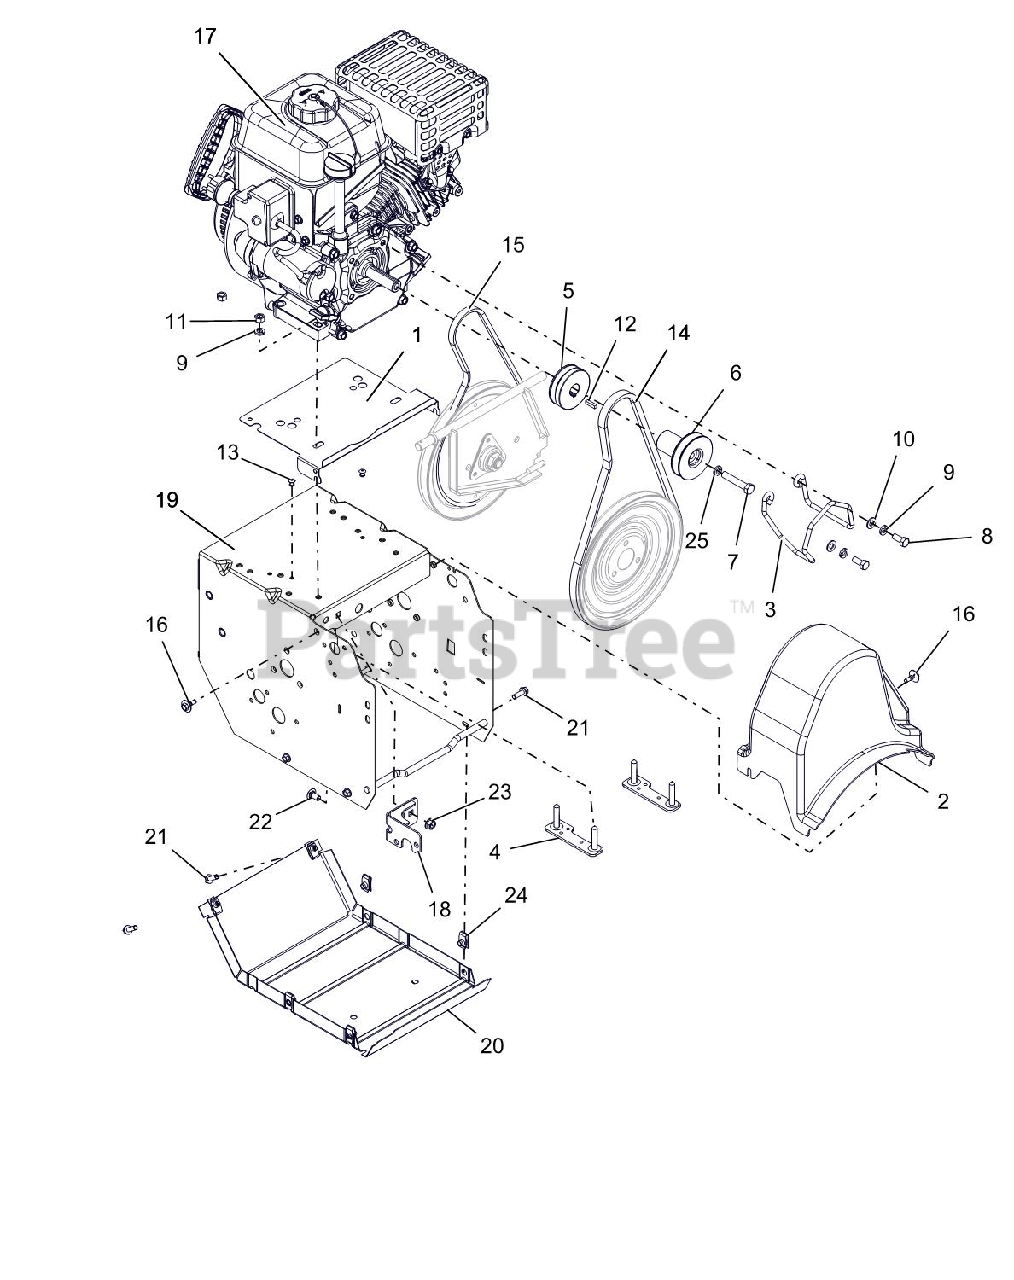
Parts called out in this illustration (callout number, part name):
1	BAFFLE, COMPACT
2	COVER, COMPACT BELT
3	FINGER, BELT
4	STRAP, ENGINE BOLT-WELDMENT
5	SHEAVE, TRACTION-COMPACT TRACK
6	SHEAVE,AUGER 3/4" PM
7	BLT-HEX .38-24X2.0 YWZC
8	BLT-HEX .31-24X.75 YWZC GR5
9	WSHR-LK .312X.097 HVY YWZC
10	@WSHR-FL-STL.344X.688X.065YWZC
11	@NUT-HEX .31-18 YWZC
12	KEY-SQ .188X.75X.188
13	RVT-POP .187 YZ
14	V-BELT, HA-RAW EDGE
15	V-BELT, 3L-WRAPPED
16	SCR-TAP .25-20X.5 CAPTIVE
17	ENGINE, ARIENS AX208 240V/60W
18	WELDMENT, FRAME BRACKET
19	FRAME, MAIN-WELDMENT
20	COVER, BOTTOM
21	BLT-HEX .25-20X.75 HWH YZ GR5
22	@BLT-RHDSSQNK .31-18X.62 G5YZ
23	@NUT-LK-TOP-FLG .31-18 YWZC
24	NUT-RTNR .25-20X.56
25	WSHR-LK .312X.097 HVY YWZC
